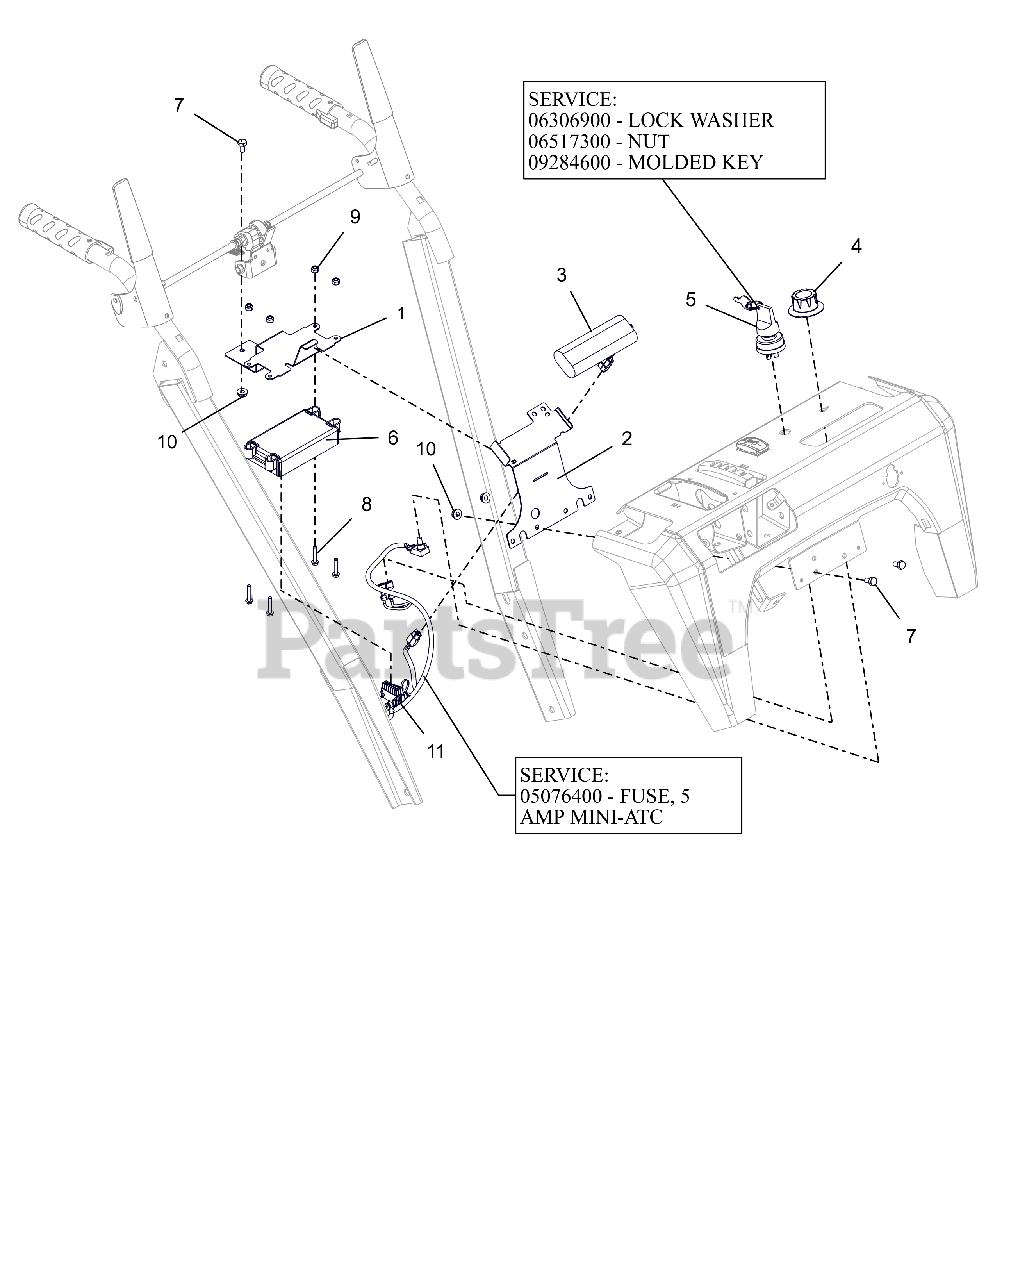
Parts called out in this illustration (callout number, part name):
1	BRACKET, ENGINE EFI-LCT LOWER
2	BRACKET, ENGINE EFI-LCT UPPER
3	BATTERY, SNOW EFI - 7.2V
4	KNOB, CONTROL - 2.063 ID
5	IGNITION SWITCH ASM - 2 POS
5	WSHR-LK-INT .625X.045 YWZC
5	NUT-PANEL .625-32 GRECO
5	KEY W/ SHIELD
6	ECU SERVICE LCT/CSI - 420CC
7	BLT,HEX .25-20X.50 G5 ZCC
8	BLT, HWH #10-24X1.00 ZCC
9	NUT-LK-NYL #10-24 G2 ZCC
10	NUT-LK-TOP-FLG .250-20 GF ZCC
11	HARNESS,WIRE - EFI ECU
11	FUSE, 5 AMP MINI-ATC
